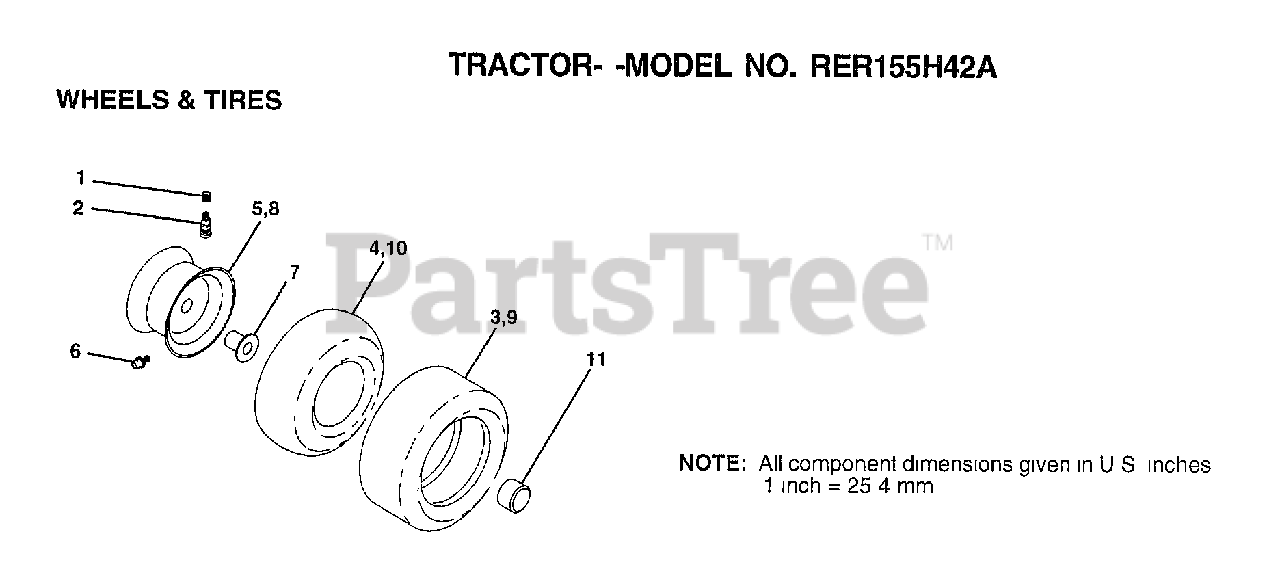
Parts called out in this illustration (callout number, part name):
1	VALVE CAP
2	VALVE STEM LT
4	TUBE.5.3/4.5/6
5	"RIM ASM 6"" FRT"
6	FITTING LT
7	"FLANGE, BEARING"
8	"RIM AS 8"" REAR"
9	TIRE.20X8-8
10	TUBE.18X9.5-8
11	HUB CAP
